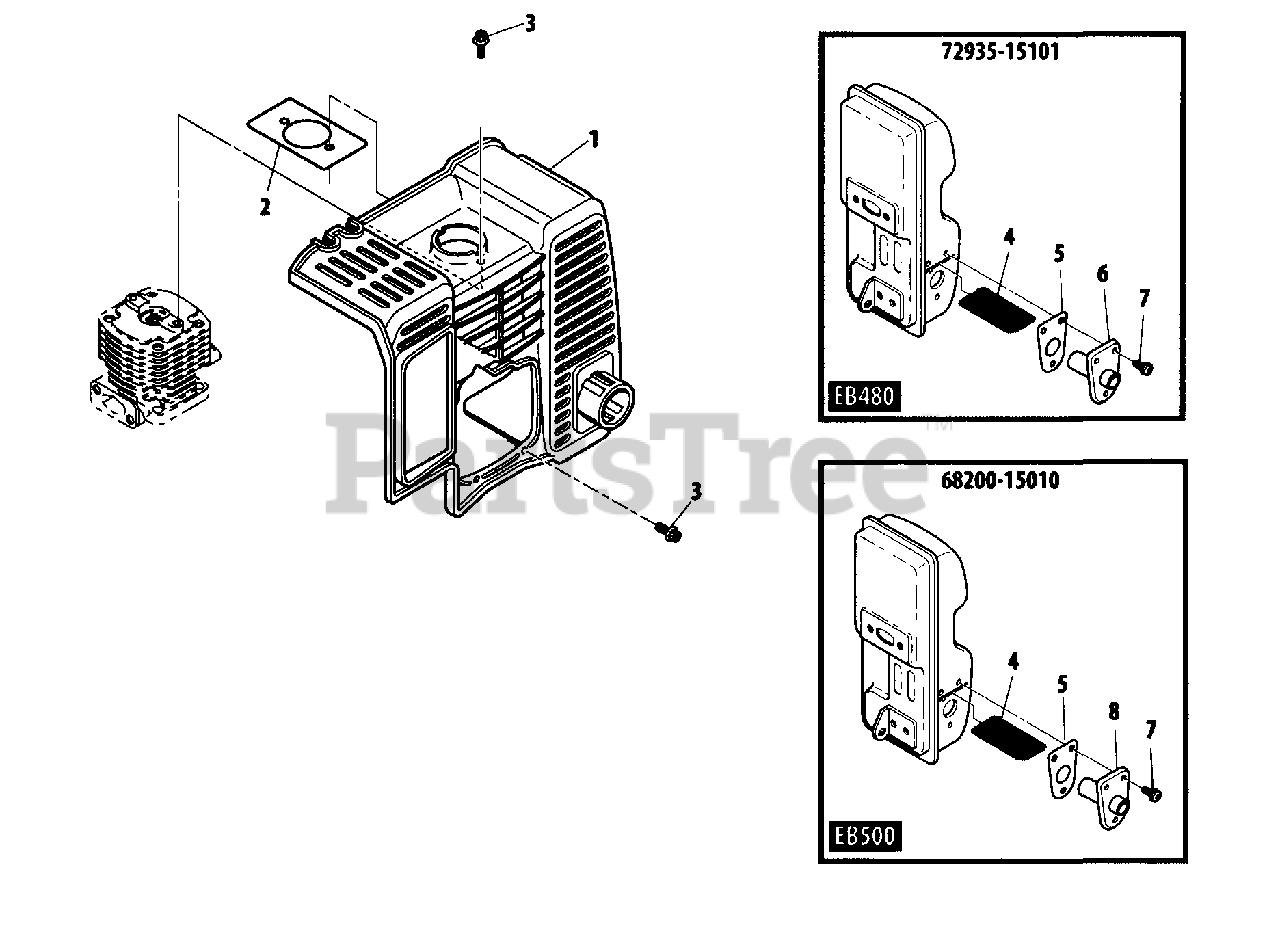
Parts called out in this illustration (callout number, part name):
1	COVER, ENGINE
2	GASKET
3	SCREW - 5X16
4	SCREEN, SPARK ARRESTOR
5	GASKET, EXHAUST
6	GUIDE, EXHAUST
7	SCREW - 4X10
7	SCREW - 4X12
8	PIPE, EXHAUST
68200-15010	MUFFLER ASSY
72935-15101	MUFFLER ASSY
